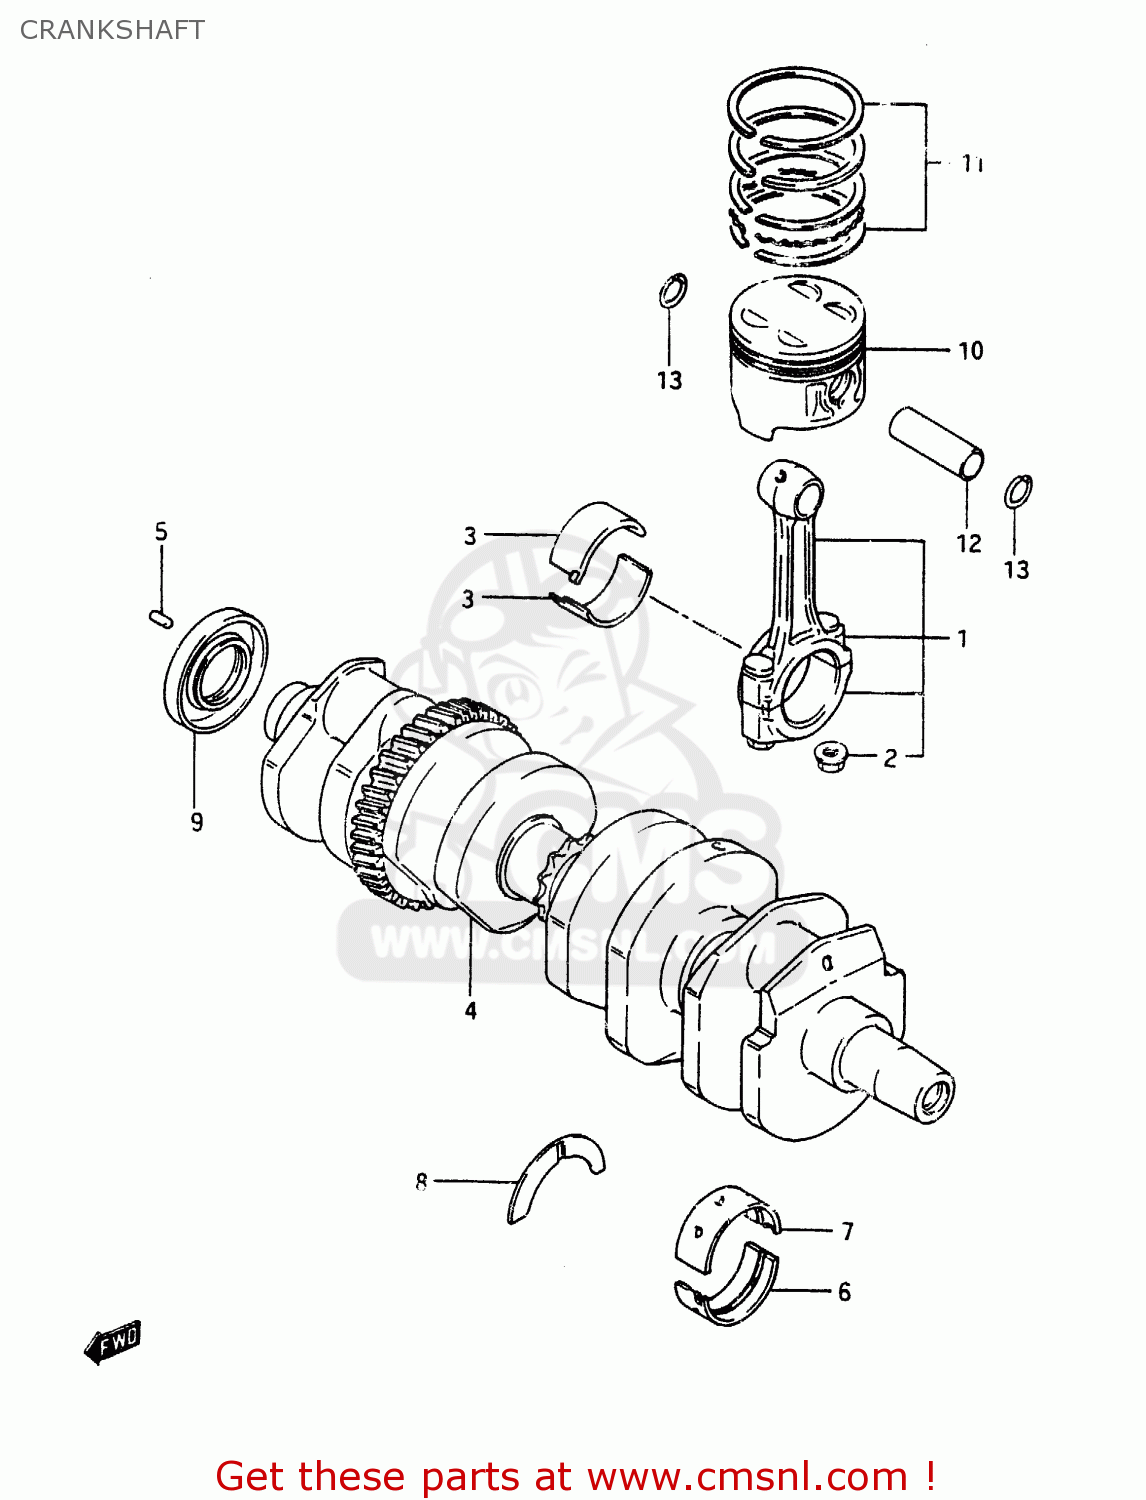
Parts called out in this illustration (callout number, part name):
1	ROD ASSEMBLY,CONNECTING
2	NUT
3	METAL,CRANK PIN
4	CRANKSHAFT ASSEMBLY
5	PIN
6	METAL,CRANKSHAFT (GREEN)
7	METAL CRANKSHAFT (GREEN)
8	PLATE,CRANK THRUST
9	SEAL,OIL(30X60X8)
10	PISTON
11	RING SET,PISTON
12	PIN,PISTON
13	CIRCLIP,PISTON PIN
